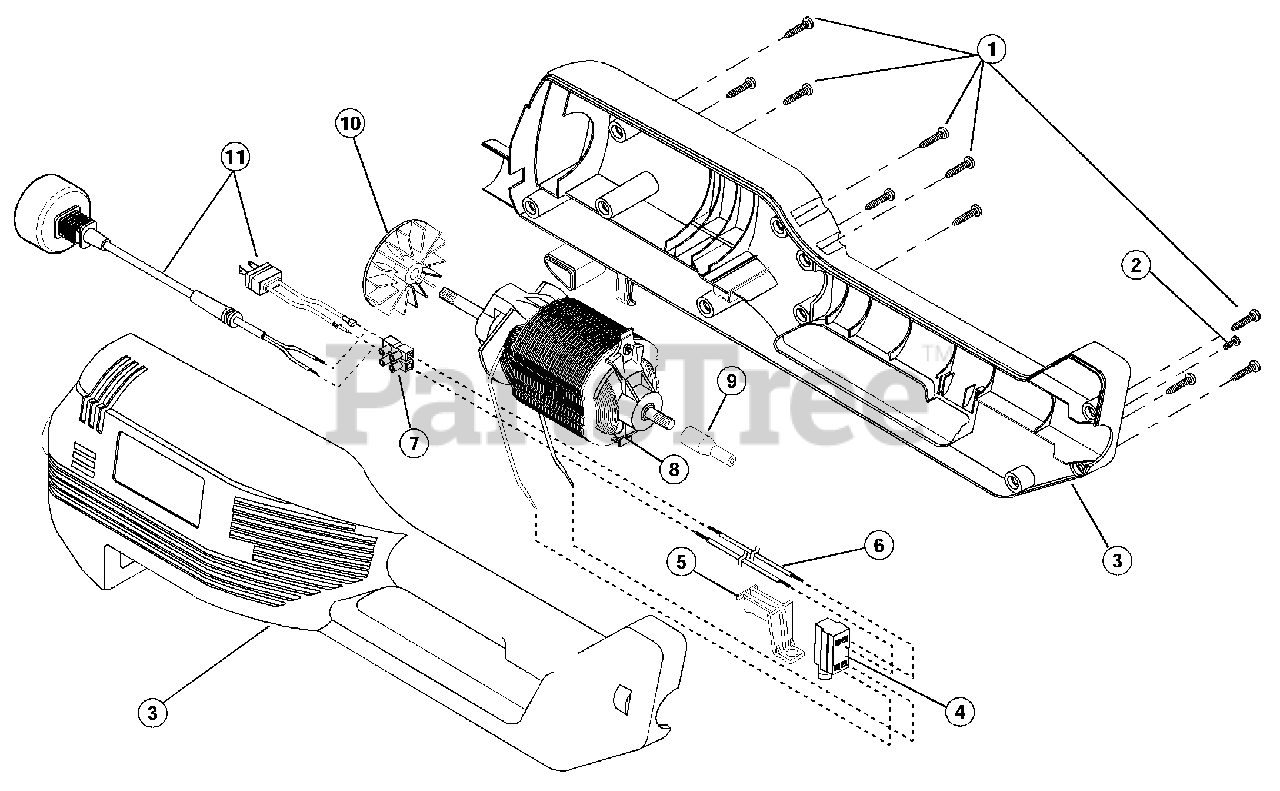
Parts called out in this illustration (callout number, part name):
1	Screw, Housing Set (Qty. 11)
2	Anti-Rotation Screw
3	Motor Housing Assembly
5	Trigger
6	Lead Wires
7	Terminal Block
8	Motor Assembly
10	Cooling Fan
11	Recessed Plug Assembly
